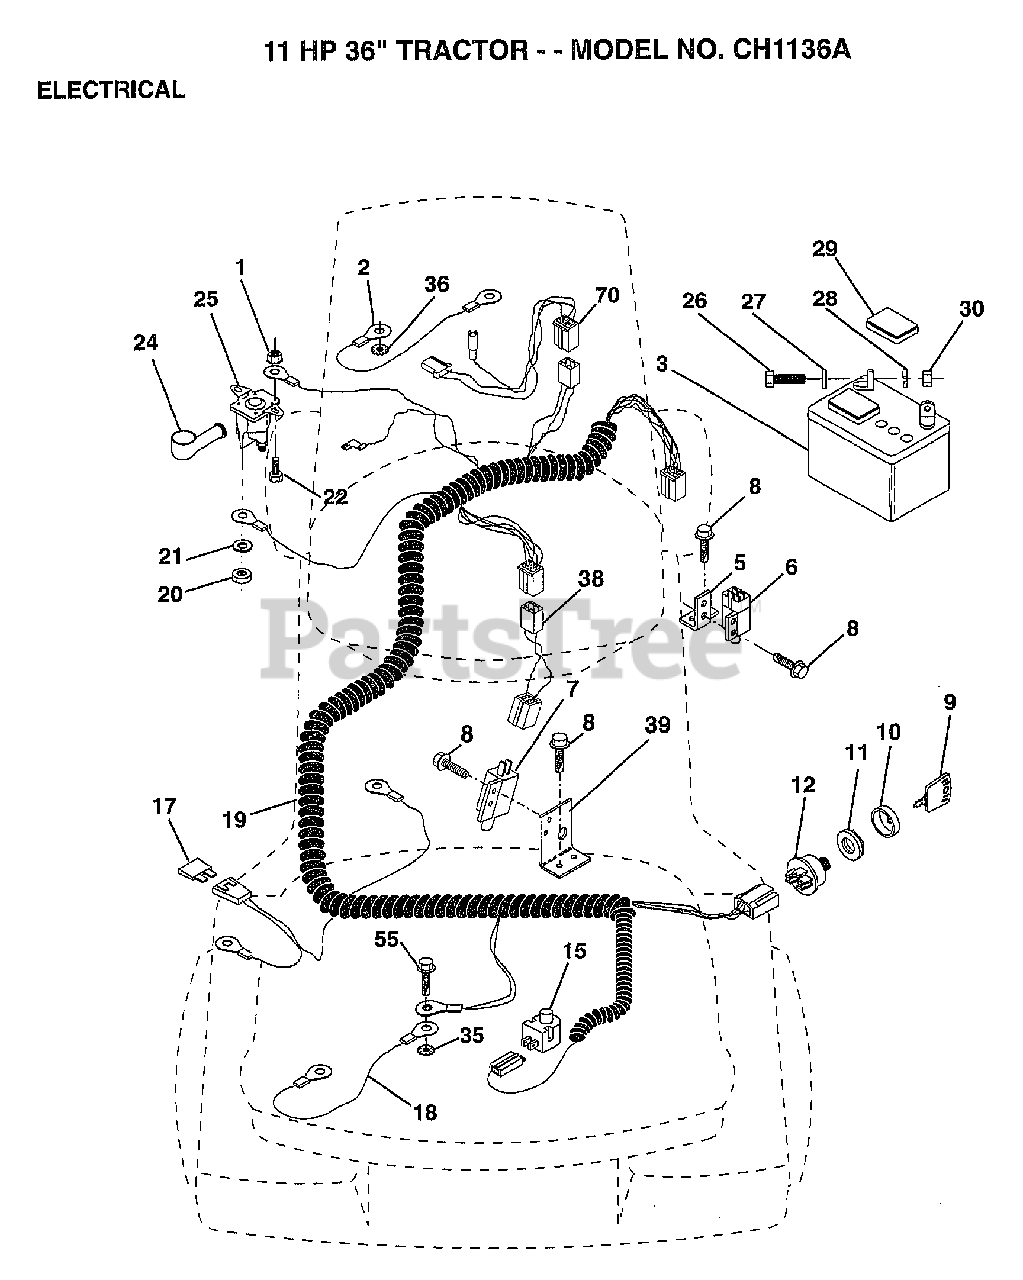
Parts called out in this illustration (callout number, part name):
1	NUT
2	CABLE ASM.
5	BRACKET LT
6	SWITCH INTERLOCKT
7	SWITCH-INTER. GT
8	SCREW
9	KEY STEEL DELTA
10	COVER KEY SWITCH
15	SWITCH SEAT
17	FUSE HYT
18	CABLE ASSY
19	HARNESS IGNITION
20	NUT
22	BOLT
26	BOLT LT
27	WASHER
28	LOCKWASHER
29	"CAP,BATTERY "
35	LOCKWASHER.5/16.E
36	LOCKWASHER
38	ADAPTER.HARN.SERV
39	BRACKET SWT CLUTC
55	SCREW LT
70	HARNESS ENG DUAL
